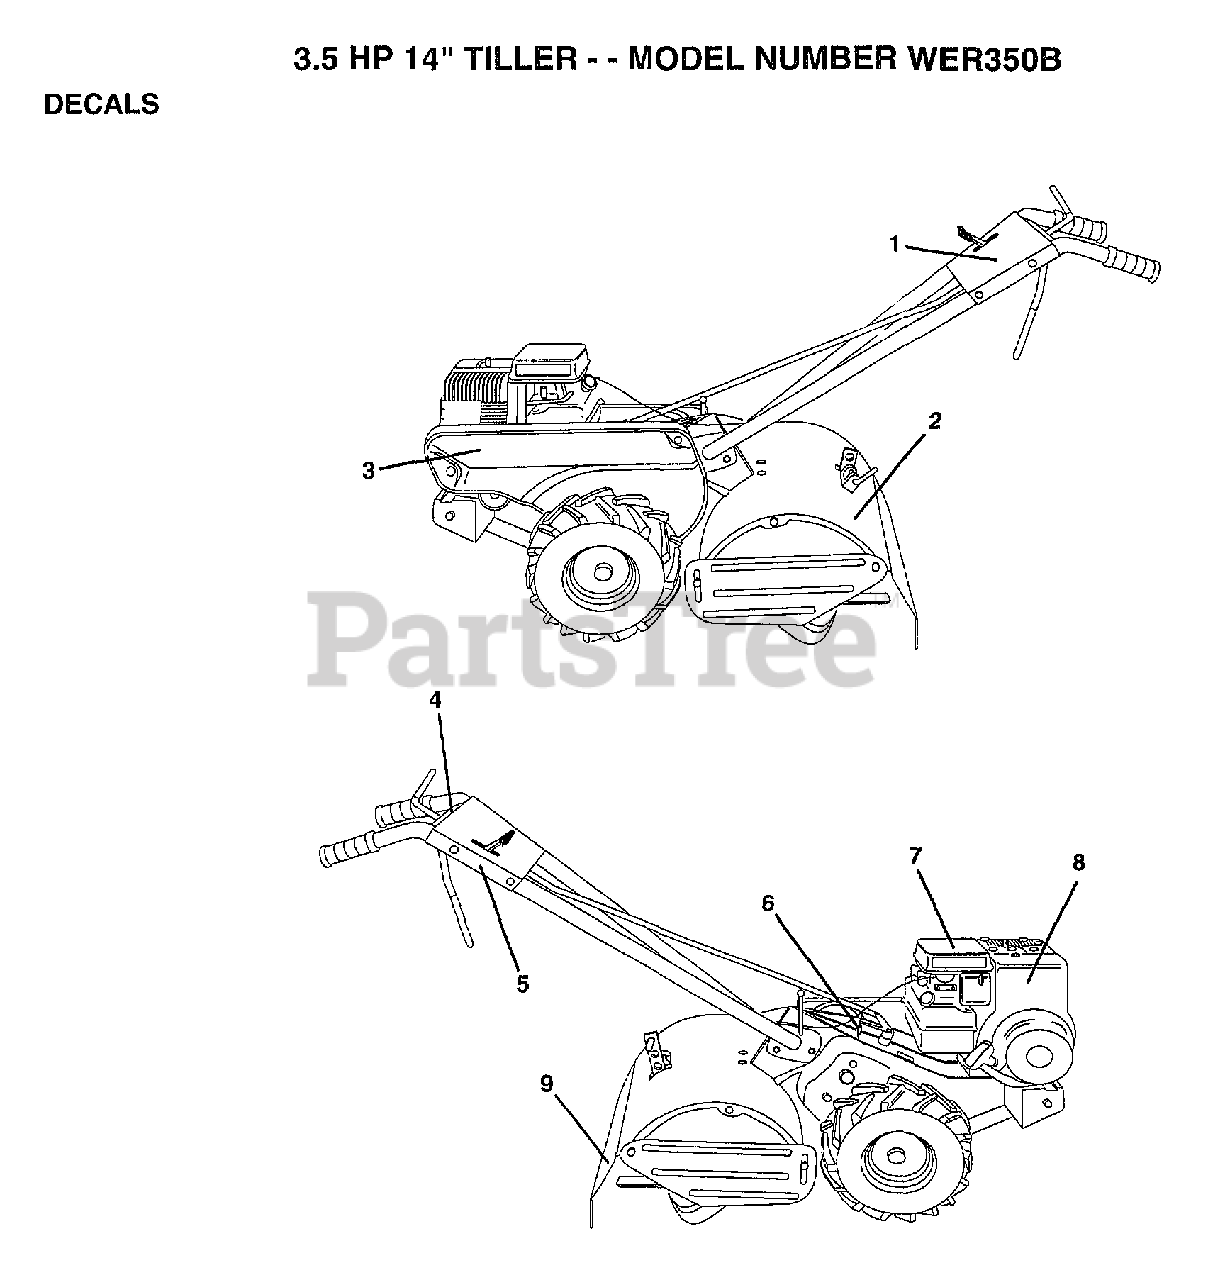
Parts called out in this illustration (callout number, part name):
1	DECAL.PNL.CTRL.
2	DECAL.SHIELD.TINE
3	DECAL BELT GUARD
4	DECAL.CONTROL
5	DECAL.HAND.PLACE
6	DECAL CRT
7	DECAL.CAUTION.E/S
8	"DECAL,ENG HP"
9	DECAL.WARN.ROT.TI
